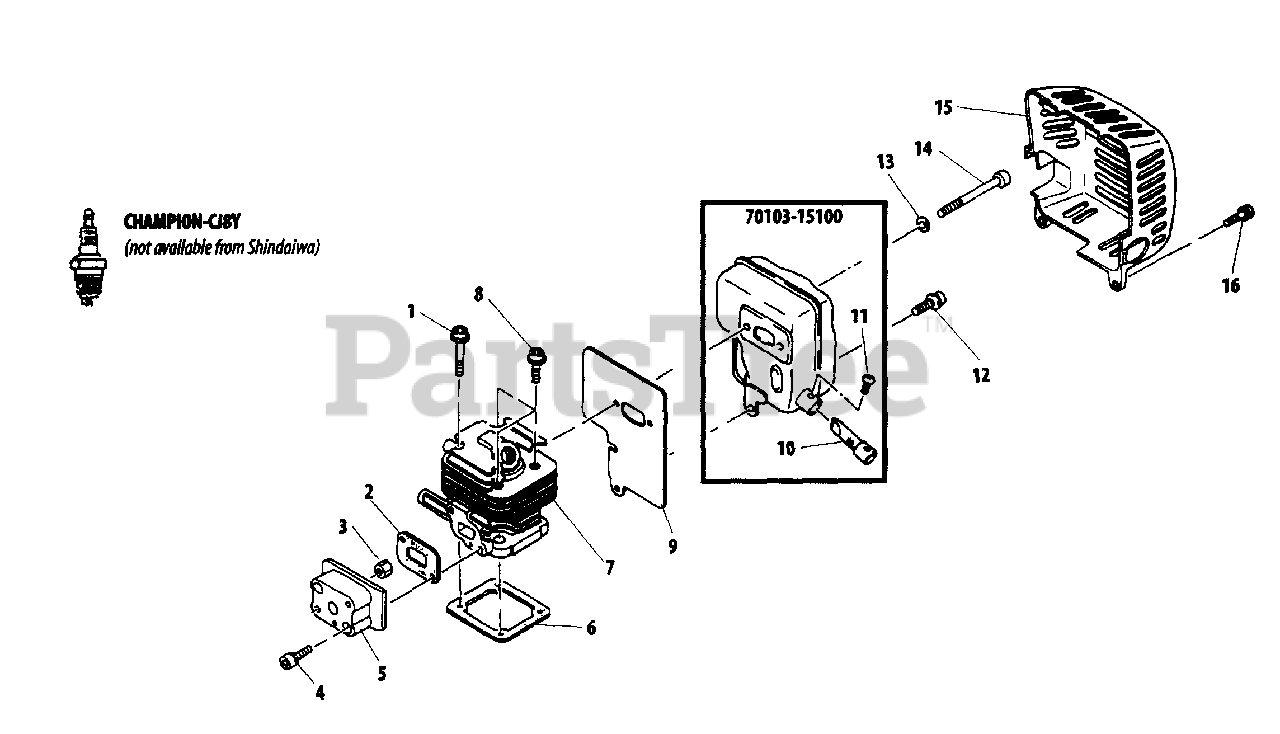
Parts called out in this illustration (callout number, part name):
1	SCREW - 5X30
2	GASKET, INTAKE
4	SCREW - 5X20
5	INSULATOR
6	GASKET, CYLINDER
7	CYLINDER
8	SCREW - 5X16
9	GASKET, EXHAUST
10	SCREEN, SPARK ARRESTOR
11	SCREW - 3X6
12	SCREW - 5X12
13	WASHER - 5
14	SCREW - 5X55
15	COVER, MUFFLER
16	SCREW - 5X16
